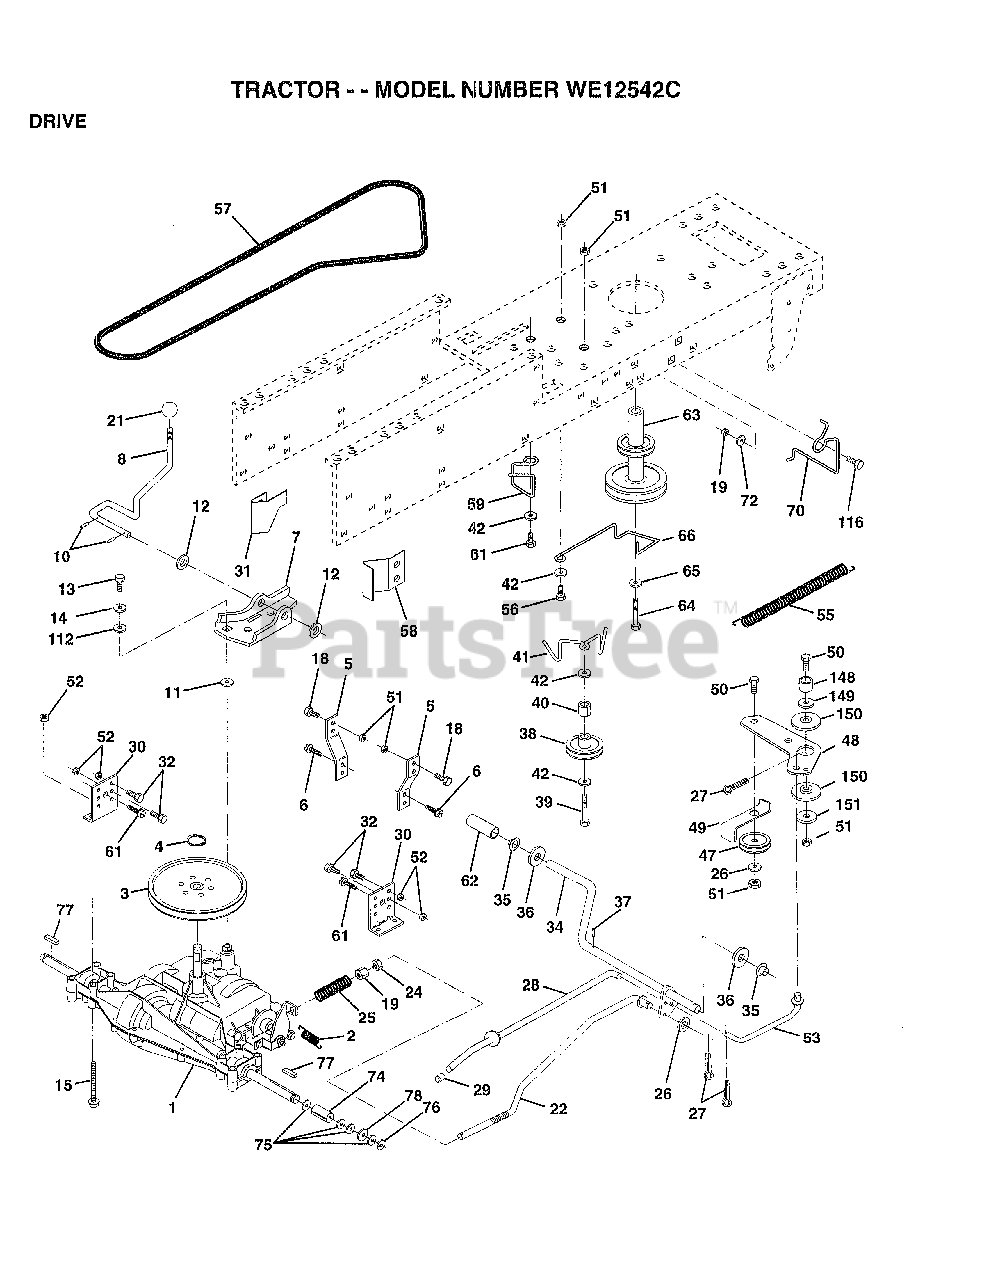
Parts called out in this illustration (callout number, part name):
2	SPRING.BRAKE.RETU
3	PULLEY TRANS
5	STRAP TORQUE
6	SCREW
7	BRKT.SADDLE.SHIFT
8	SHIFT ROD
10	PIN COTTER 1/8
11	WASH-SHFT PLT LT
12	WASHER
13	BOLT.1/4-28.W/PAT
14	LOCKWASHER
15	BOLT.HX.FLG.5/16
18	BOLT
19	NUT
21	KNOB T (1/2-HOLE)
22	BRAKE ROD
24	NUT
25	SPRING ROD LT
26	WASHER
27	COTTER PIN
28	ROD.BRAKE.PARK.LT
29	PLUNGER CAP T
30	TRANSAXLE MTG BKT
31	"KEEPER,BELT LH T"
32	BOLT
34	SHAFT ASM-PEDAL F
35	NYLON BEARING
36	WASHER LT
38	PULLEY.IDLER.FLAT
39	BOLT
40	SPACER T
42	WASHER
48	BELLCRANK.CLUTCH
49	RETAIN BELT
53	"LINK, CLUTCH T"
55	"SPRING, RETURN LT"
57	"V-BELT,95.3"
58	"KEEPER,BELT RH T"
59	KEEPER BELT CNTSP
61	SCREW
62	PEDAL COVER T
63	PULLEY.ENGINE
64	BOLT
65	LOCKWASHER
66	KEEPER-BELT
70	KEEPER BELT ENG
72	WASHER
74	SPACER LT
75	WASHER
76	E-RING LT
77	SQUARE KEY
78	WASHER
112	WASHER LT
116	BOLT RDHD 3/8-16
149	SPACER RETAINER
150	BUSHING.NYLON
151	WASHER
